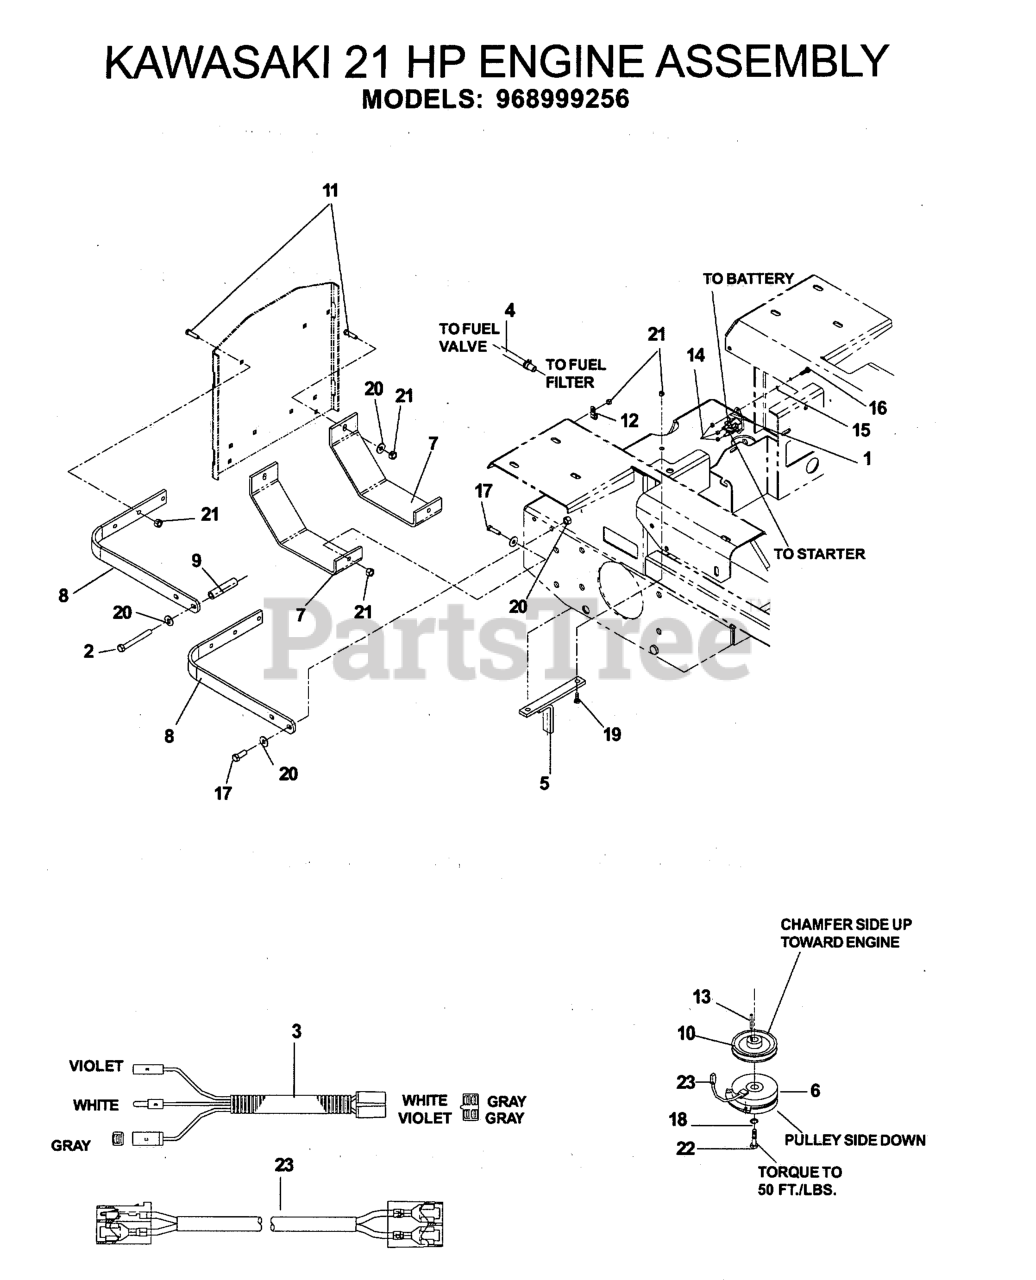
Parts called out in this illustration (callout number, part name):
2	HCS 5/16C X 4
3	KAW PIGTAIL
4	FUEL LINE 29.5"
5	CLUTCH TIE DOWN
6	CLUTCH-200 FT LB(RPLS 5218-102
7	SKID PLATE
8	ENGINE SHROUD BRKT
11	RHSSNB 5/16C X 1.0
12	DOUBLE TUBE CLAMP
13	KEY, 1/4 SQ X 1 1/4
14	NUT.1/4-20.HEX.NYLOC.ZD
15	WASHER 1/4 INT TOOTH
16	HCS 1/4C X 5/8
17	HCS 5/16C X 1
18	WASHER 7/16 LOCK
19	HCS 5/16C X 1 3/4
20	WASHER 5/16 FLAT
21	NUT 5/16 NYLOC
22	BOLT 7/16F X 2 1/2
23	CLUTCH HARNESS
